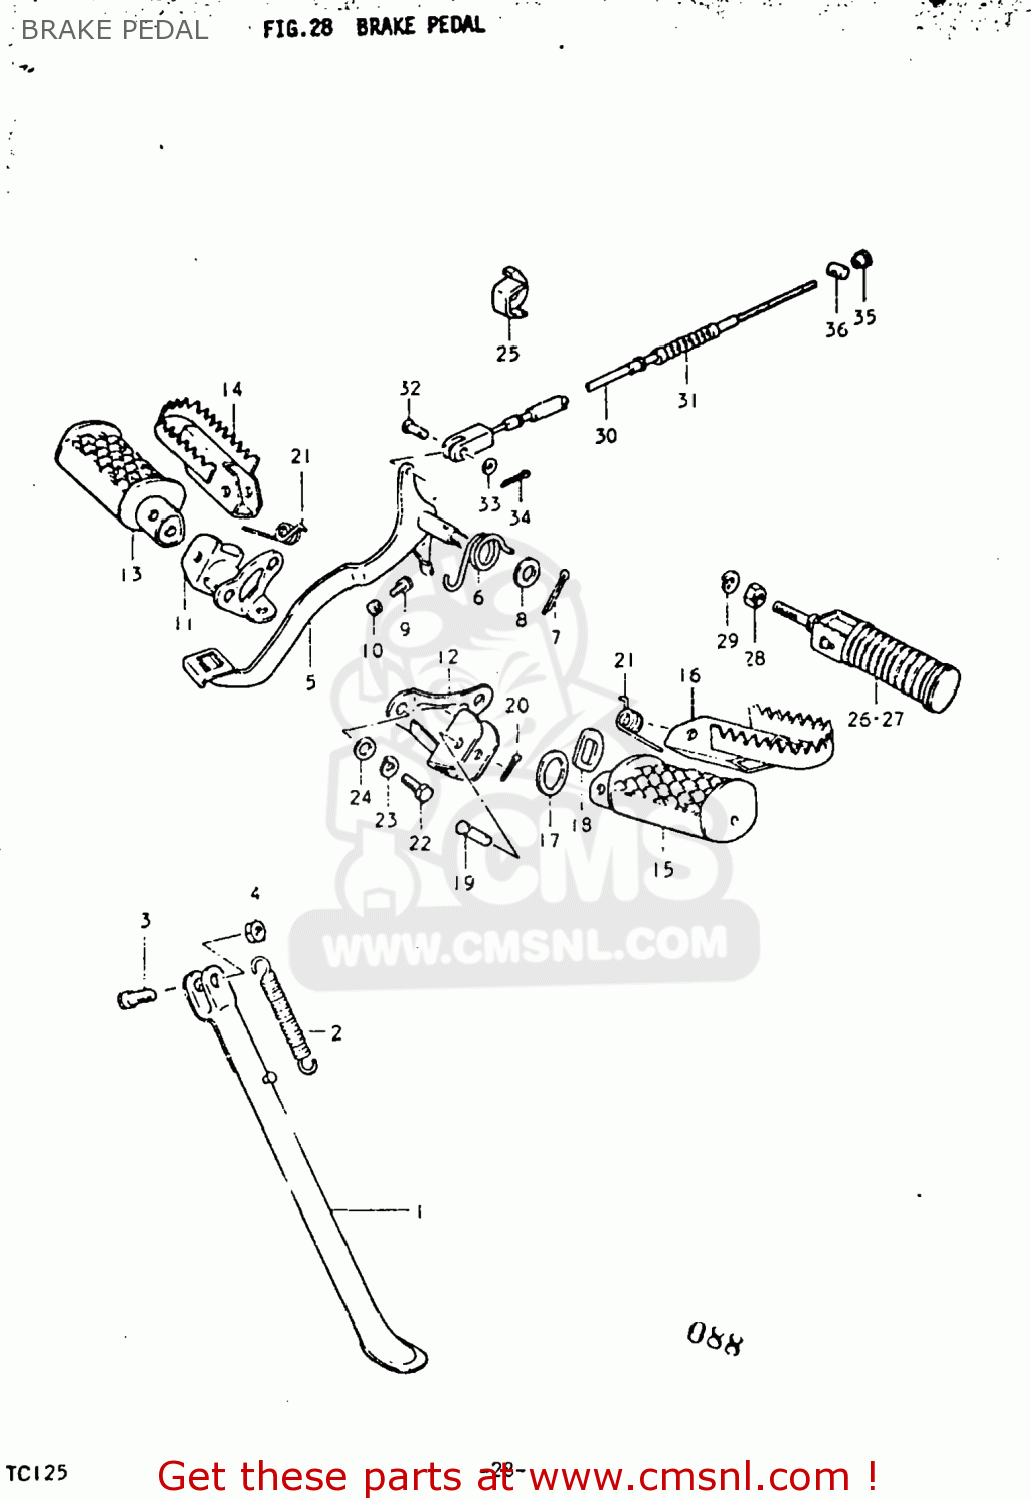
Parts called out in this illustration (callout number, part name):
1	STAND,SIDE
2	SPRING
3	BOLT(10X30)
4	NUT
5	PEDAL,BRAKE
6	SPRING
7	COTTER PIN
8	WASHER(15.5X26X2.3)
9	BOLT
10	NUT
11	BAR,FRONT FOOTREST
12	HOLDER,FRONT FOOTREST
13	RUBBER,FOOTREST,RIGHT
14	RUBBER,FOOTREST,RIGHT
15	RUBBER,FOOTREST,LEFT
16	RUBBER,FOOTREST,LEFT
17	WASHER
18	WASHER
19	PIN
20	PIN 20X20
21	SPRING
22	BOLT
23	LOCK WASHER
24	WASHER
25	HOLDER
26	FOOTREST ASSEMBLY,REAR
27	FOOTREST ASSY,PILLION
28	NUT
29	WASHER,LOCK 12
30	CABLE,RR BRAKE
31	SEAL,DUST
32	PIN
33	WASHER
34	PIN
35	NUT
36	PIN(11X18)
